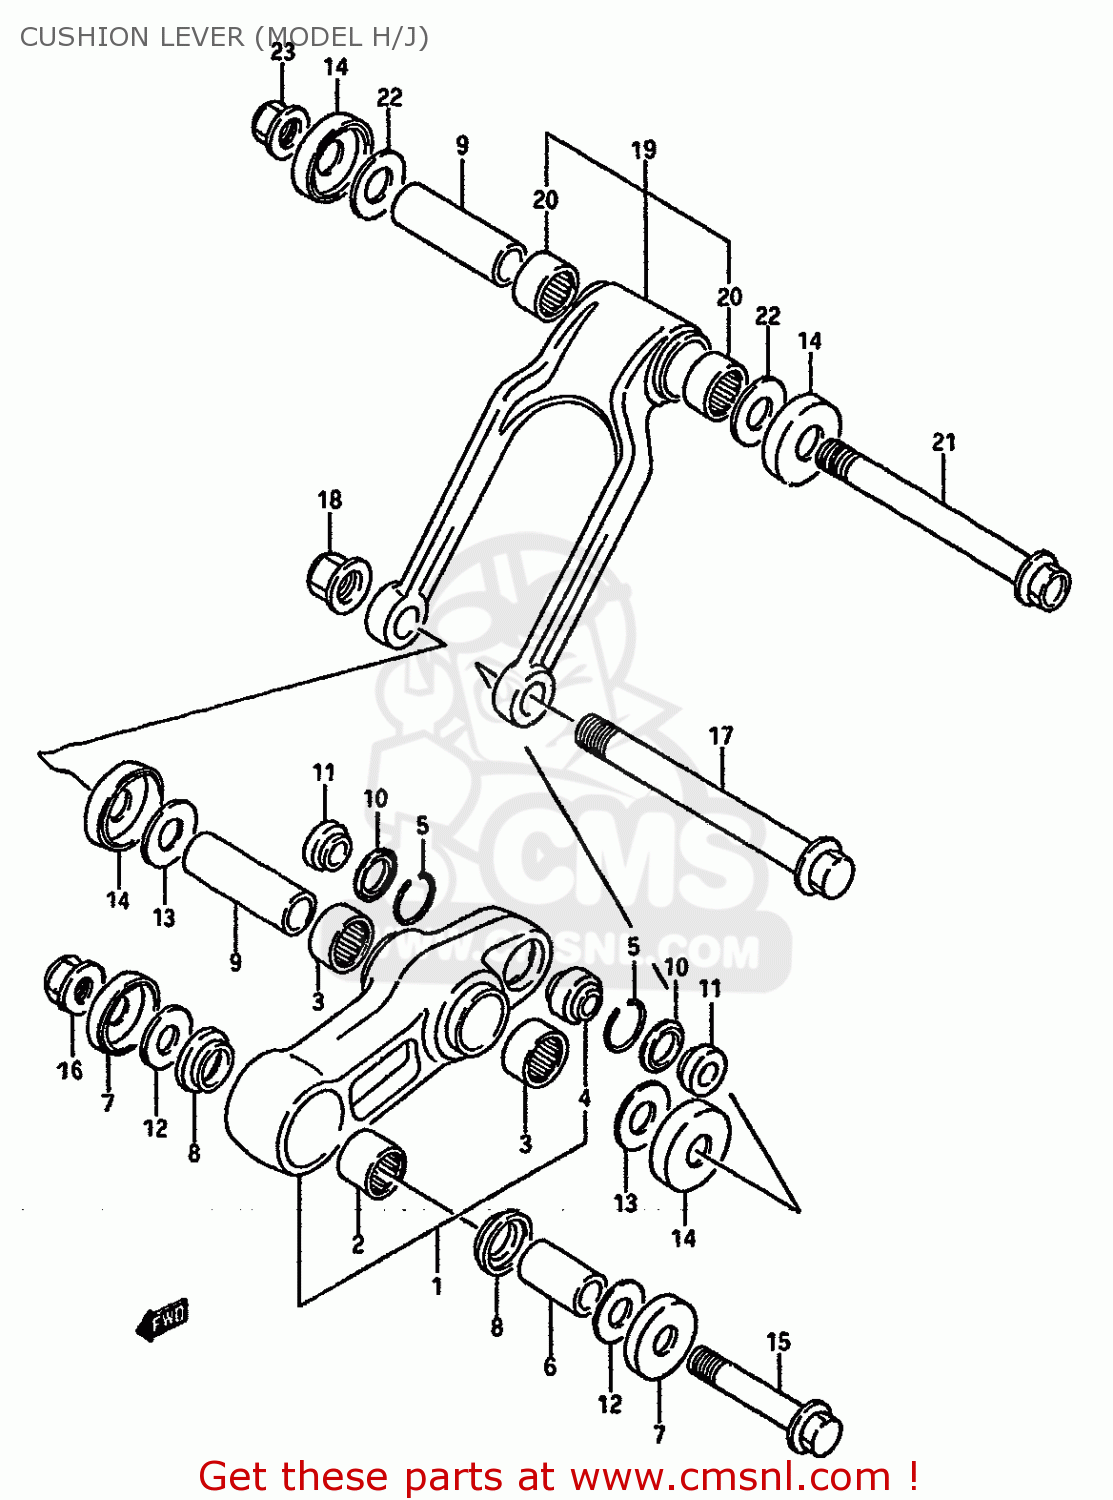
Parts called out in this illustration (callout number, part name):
1	LEVER SET,REAR CUSHION
2	BEARING(20X27X25)
3	BEARING(20X27X20)
4	BEARING,RR CUSHION LEVER
5	RING
6	SPACER,REAR CUSHION LEVER
7	COVER,REAR SWING ARM DUST
8	COLLAR,RR CUSHION LEVER FR
9	SPACER,REAR CUSHION LEVER
10	SEAL,DUST RR SHOCK ABSORBER
11	COLLAR
12	WASHER
13	WASHER
14	DUST SEAL,RR C
15	BOLT,RR CUSHION LEVER FR
16	NUT 12MM
17	SHAFT,RR CUSHION LEVER
18	NUT
19	LEVER SET,REAR CUSHION
20	BEARING(20X27X20)
21	BOLT,REAR CUSHION ROD
22	WASHER
23	NUT
